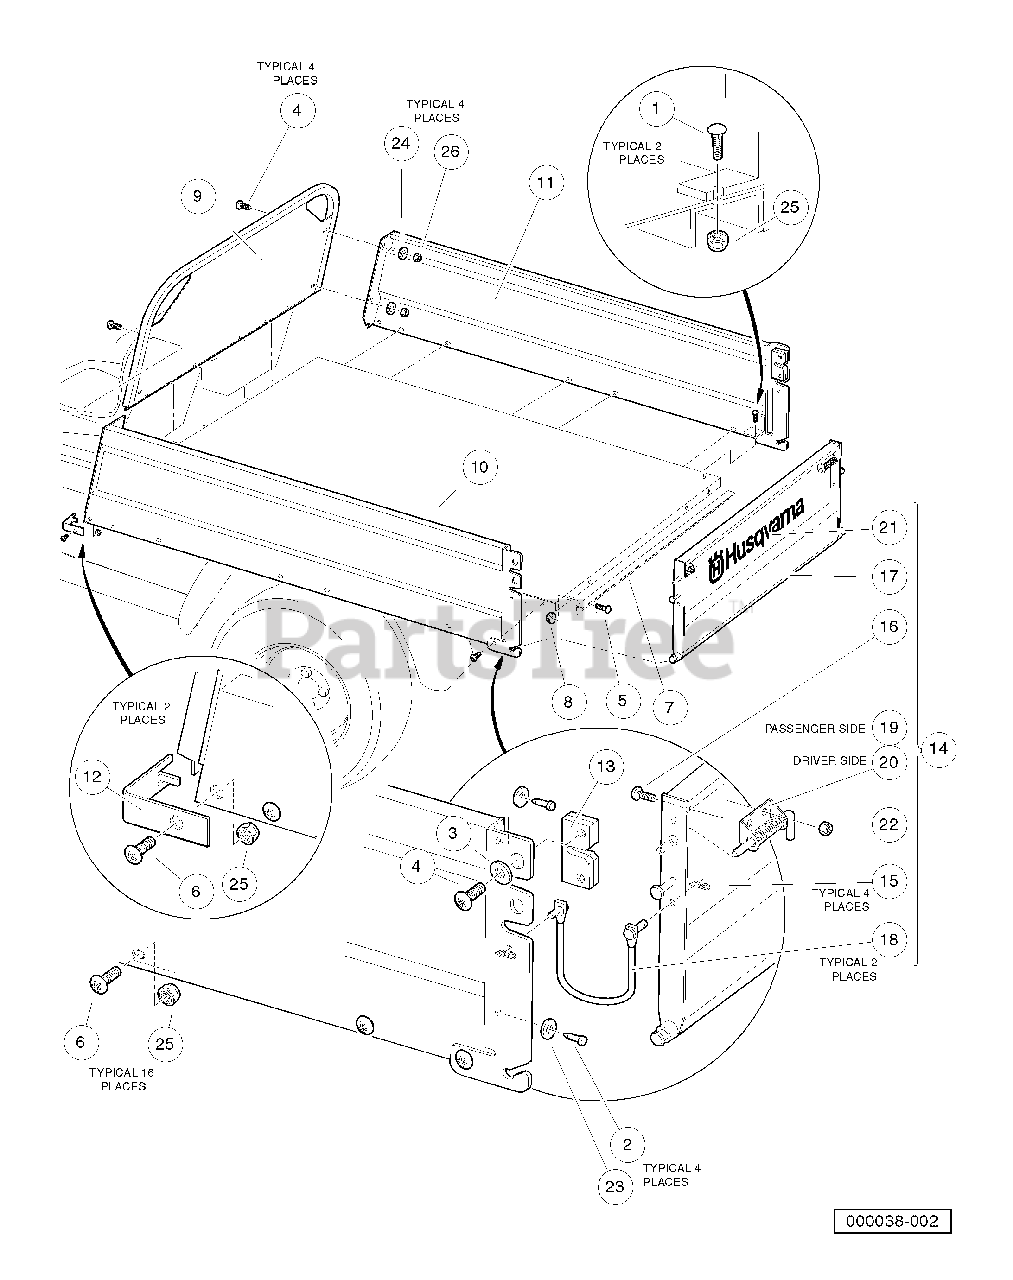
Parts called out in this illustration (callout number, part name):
1	Bolt, Carriage, 5/16-18 X 1.00
2	Bumper, Rubber
3	Washer, 1/4" Type B Flat
4	Screw, 1/4-20 X 0.75 Torx Truss-Head
5	Stud, Self-Clinching Flush Head
6	Screw, 5/16-18 X 0.88 Torx Truss-Head
7	Box Bed Tailgate Angle
8	Locknut, 5/16-18 Hex Flange
9	Front Panel Weldment
10	Left Panel Weldment
11	Right Panel Weldment
12	Front Corner Cap
13	Slam Latch
14	Assembly, Tailgate
15	Hair Pin Clip
16	Screw, 1/4-20 X 0.75 Torx Truss-Head
17	Tailgate, Weldment
18	Tether Assembly
19	Spring Latch Left
20	Spring Latch Right
21	Decal, Husqvarna, Tailgate
22	Locknut, 1/4-20 Nylon Insert
23	Washer, Rubber, 3/8
24	Washer, 1/4 Type A Narrow Flat
25	Locknut, 5/16-18 Nylon Insert
26	Locknut, 1/4-20 Nylon Insert
